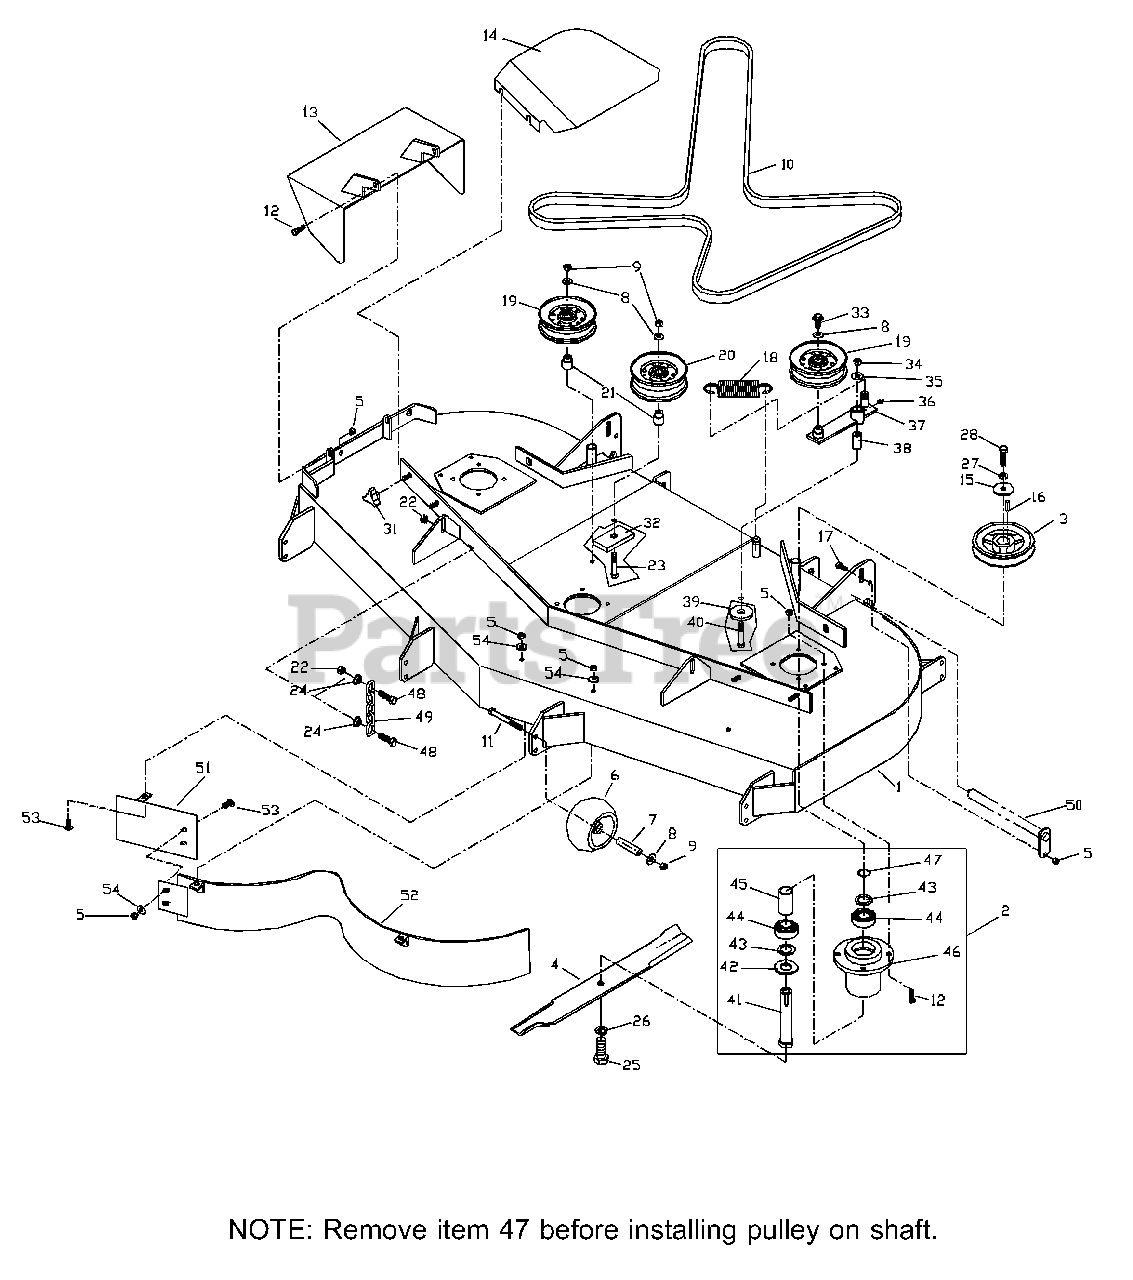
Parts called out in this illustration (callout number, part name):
1	DECK W/DECALS
2	CUTTER HOUSING ASM.
5	NUT 5/16 LOCK
8	3/8 FLAT WASHER
9	NUT 3/8 LOCK
10	BELT
11	HCS 3/8 X 3.5
12	HCS 5/16 X 1.00
13	DISCHARGE CHUTE
14	BELT SHIELD RT.
14	BELT SHIELD LT.
16	KEY 1/4 SQ.
17	HCS 5/16 X .750
19	PULLEY 1.31
20	PULLEY 1.62
21	IDLER BUSHING
22	NUT 7/16 LOCK
23	HCS 3/8 X 2.5
24	NUT 7/16 WHIZ
25	HCS 5/8F X 1.25
26	WASHER 5/8 LOCK
27	7/16 LOCK WASHER
28	HCS 7/16F X 1.5
32	PAD
33	HCS 3/8 X 1.0 SERR.
34	NUT 1/2 NYLOC
35	WASHER 1/2 FLAT
36	ZERK
38	PIVOT BUSHING
39	SUPPORT WASHER
40	HCS 1/2 X 3.25
42	MACHINE BUSHING
43	MACHINE BUSHING
44	BEARING
48	HCS 7/16 X 1.5
49	LIFT CHAIN
51	BAFFLE , CENTER
52	BAFFLE, MAIN
53	RHSNB 5/16 X 5/8
54	5/16 FLAT WASHER
